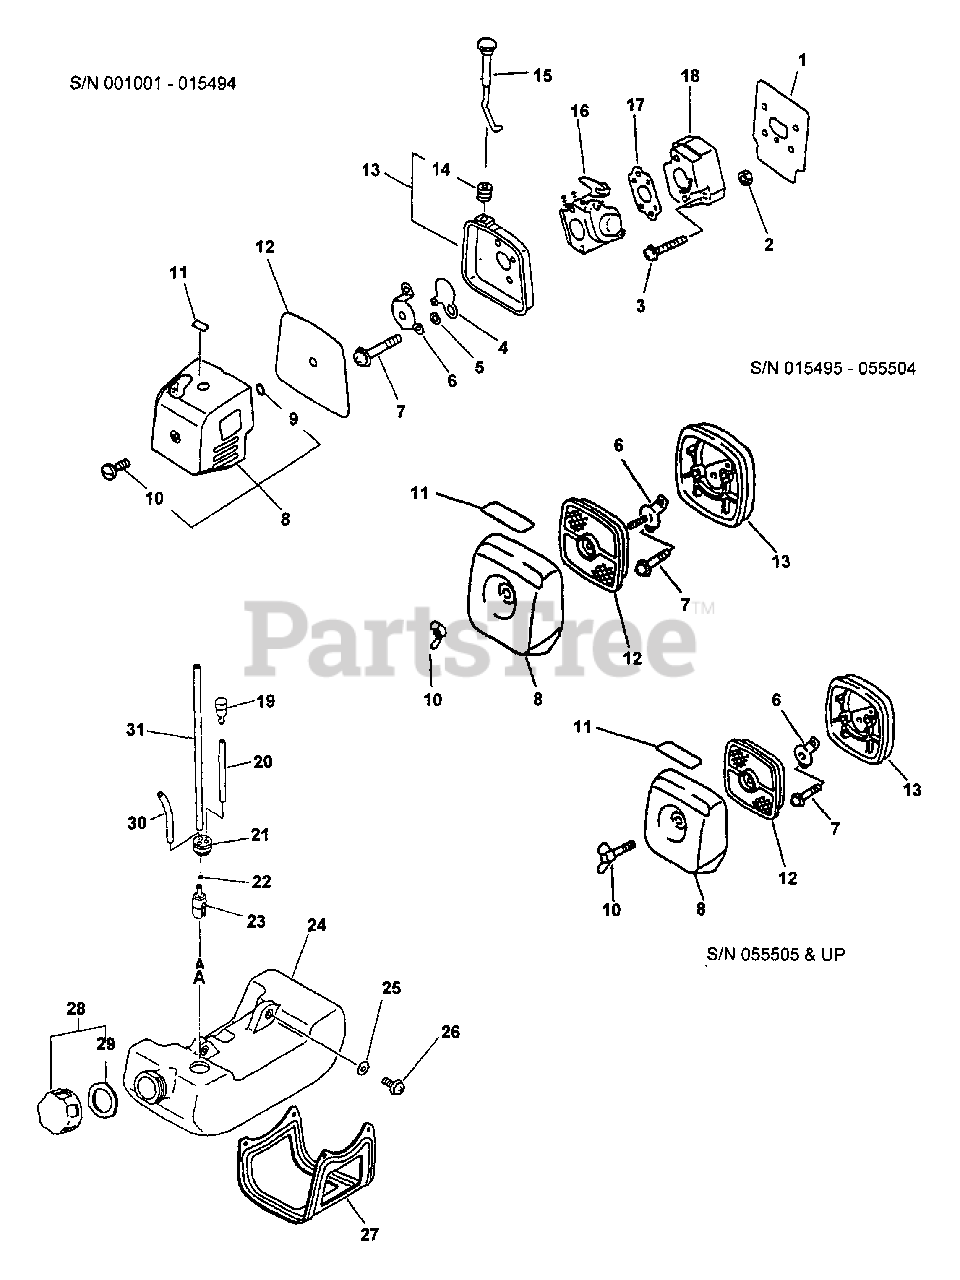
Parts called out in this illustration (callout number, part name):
1	SHIELD, INTAKE
3	SCREW - 5X20
4	SHUTTER, CHOKE
5	WASHER - 5
6	BRACKET, AIR CLEANER
6	PLATE, PREVENT
7	SCREW - 5X57
7	SCREW - 5X65
8	AIR FILTER COVER ASSY
8	COVER, AIR FILTER - BLACK
9	O-RING - 4
10	SCREW
10	WINGNUT - 6
10	THUMBSCREW
11	LABEL - CHOKE
12	FILTER, AIR
12	FILTER, AIR - SINGLE LAYER
13	CASE, AIR FILTER
13	AIR FILTER CASE ASSY
15	ROD, CHOKE
16	CARBURETOR C1U-K16
16	CARBURETOR C1U-K47
16	CARBURETOR C1U-K52
17	GASKET, INTAKE
18	INSULATOR, INTAKE
19	VENT, FUEL TANK
20	PIPE - 3X5X70 -- BLACK
21	GROMMET
22	CLIP - 6
23	FILTER, FUEL
24	TANK, FUEL
25	WASHER - 5
26	SCREW - 5X16
27	GUARD, FUEL TANK
28	CAP ASSY
29	GASKET, CAP
30	PIPE - 3X6X80 -- CLEAR
31	PIPE - 3X5X180 -- BLACK
